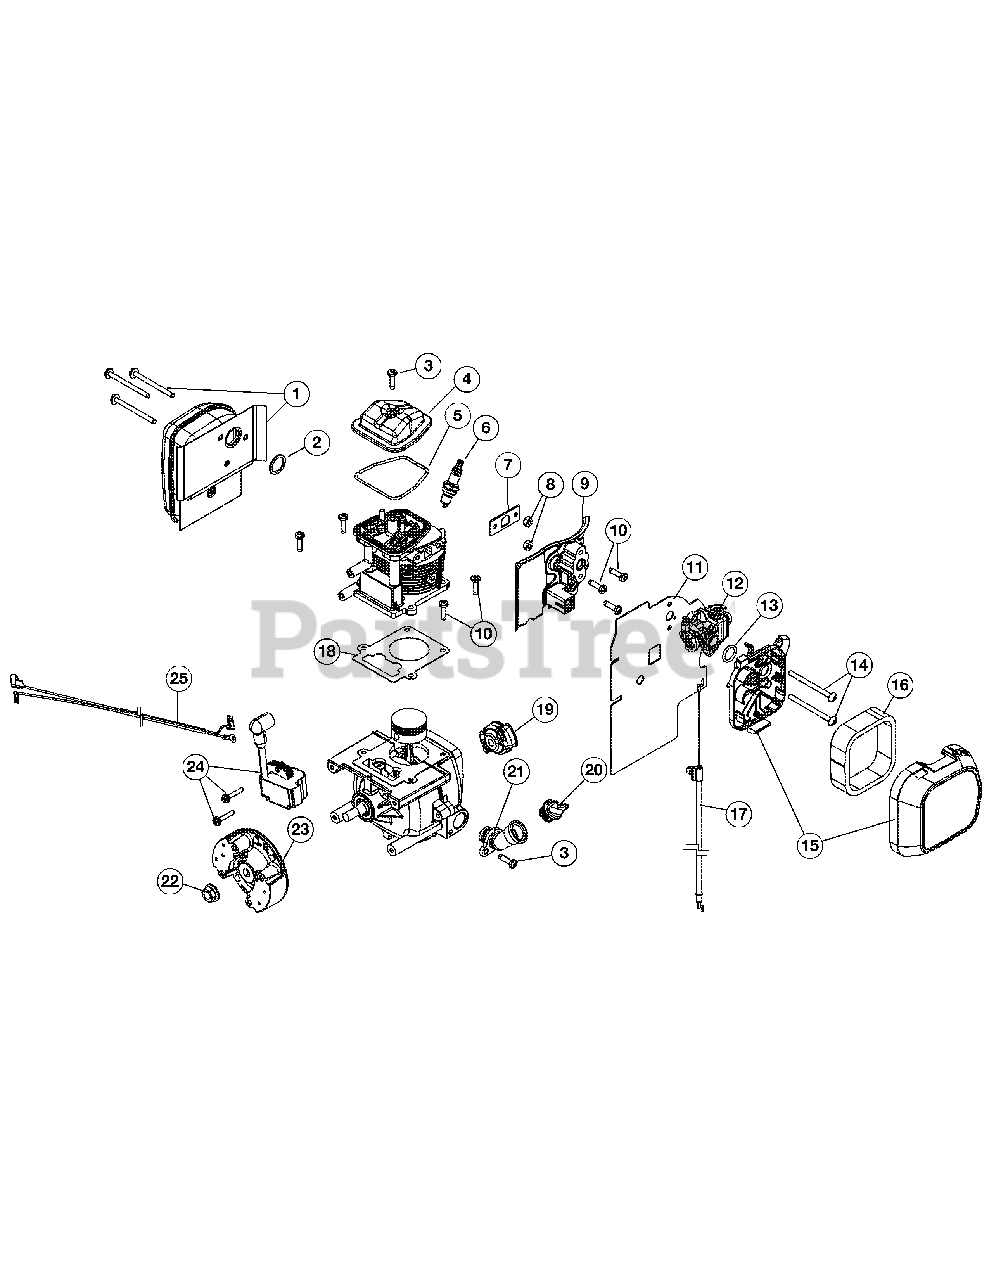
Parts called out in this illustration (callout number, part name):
1	Muffler Assembly
2	Muffler Gasket
3	Screw
4	Rocker Cover
5	Rocker Cover O-Ring
6	Spark Plug
7	Insulator Gasket
8	Nut
9	Insulator
10	Screw
11	Carburetor Gasket
12	Carburetor
13	Carburetor O-Ring
14	Screw
15	Air Cleaner Assembly
16	Air Filter
17	Throttle Cable
18	Cylinder Gasket
19	Pawl Assembly
20	Oil Plug
21	Oil Fill Tube
22	Nut
23	Flywheel Asssembly
24	Module Assembly
25	Lead Wire
